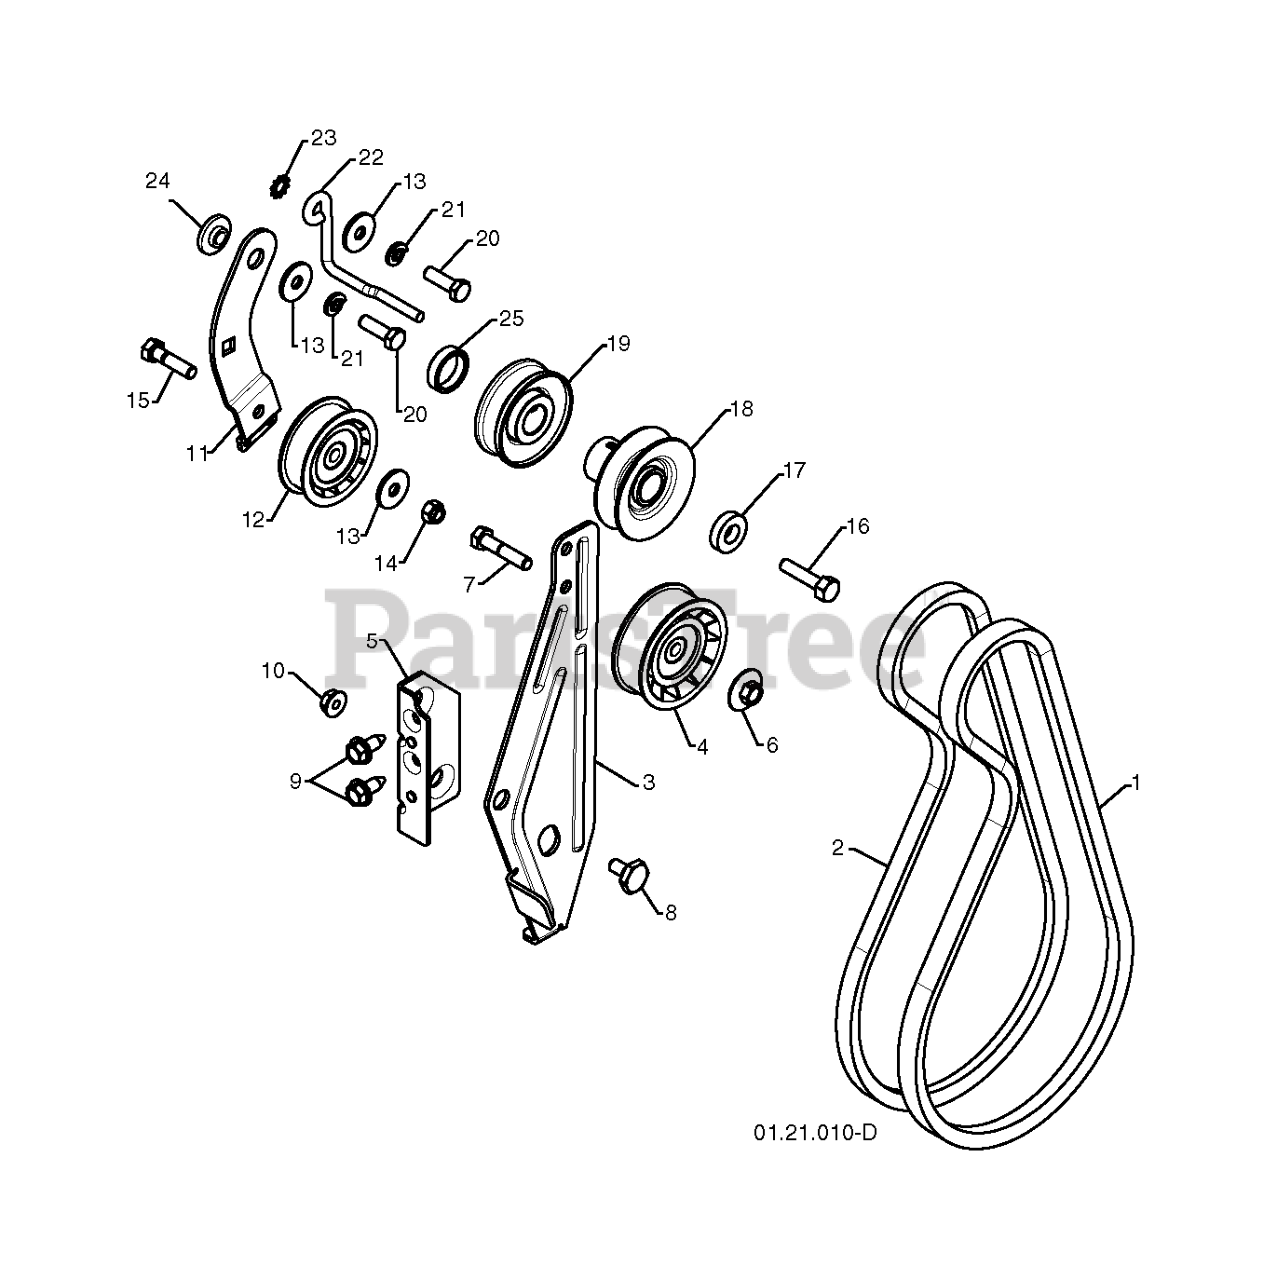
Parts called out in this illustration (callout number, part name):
1	VBELT; IMPELLER_39.09
2	TRACTION BELT
3	ARM.IDLER.BRAKE
4	PULLEY.IDLER.W/SPACER.
5	RP BRACKET.IDLER
6	NUT.FLANGE.HEX.5/16X18.BLACK
7	HEX BOLT
8	BOLT.SHOULDER.1/2X12
9	BOLT.HEX.HD.WASHER.5/16-18X.75
10	NUT.LOCK.5/16-18
11	ARM, IDLER
12	PULLEY.W/SPACER.2.25
13	STEEL WASHER
14	NUT.71038.31-18.HEX.NYLOCK
15	BOLT.5/16-18X1-1/4 FULL.THREAD
16	SCREW, HEX HD 3/8-24 X 1-3/8
17	WASHER, FLAT 3/8
18	PULLEY.ENG.IMPELLER.SNOW
19	PULLEY,ENGINE TRACTION DRIVE
21	WASHER.LOCK.HVY.HLCL.SPR.5/16
22	GUIDE.BELT.HYDRO.H
23	WASHER EXT TOOTH LOCK 5/16
24	RP BUSHING, IDLER PIVOT
25	SPACER.ENGINE.PULLEY
